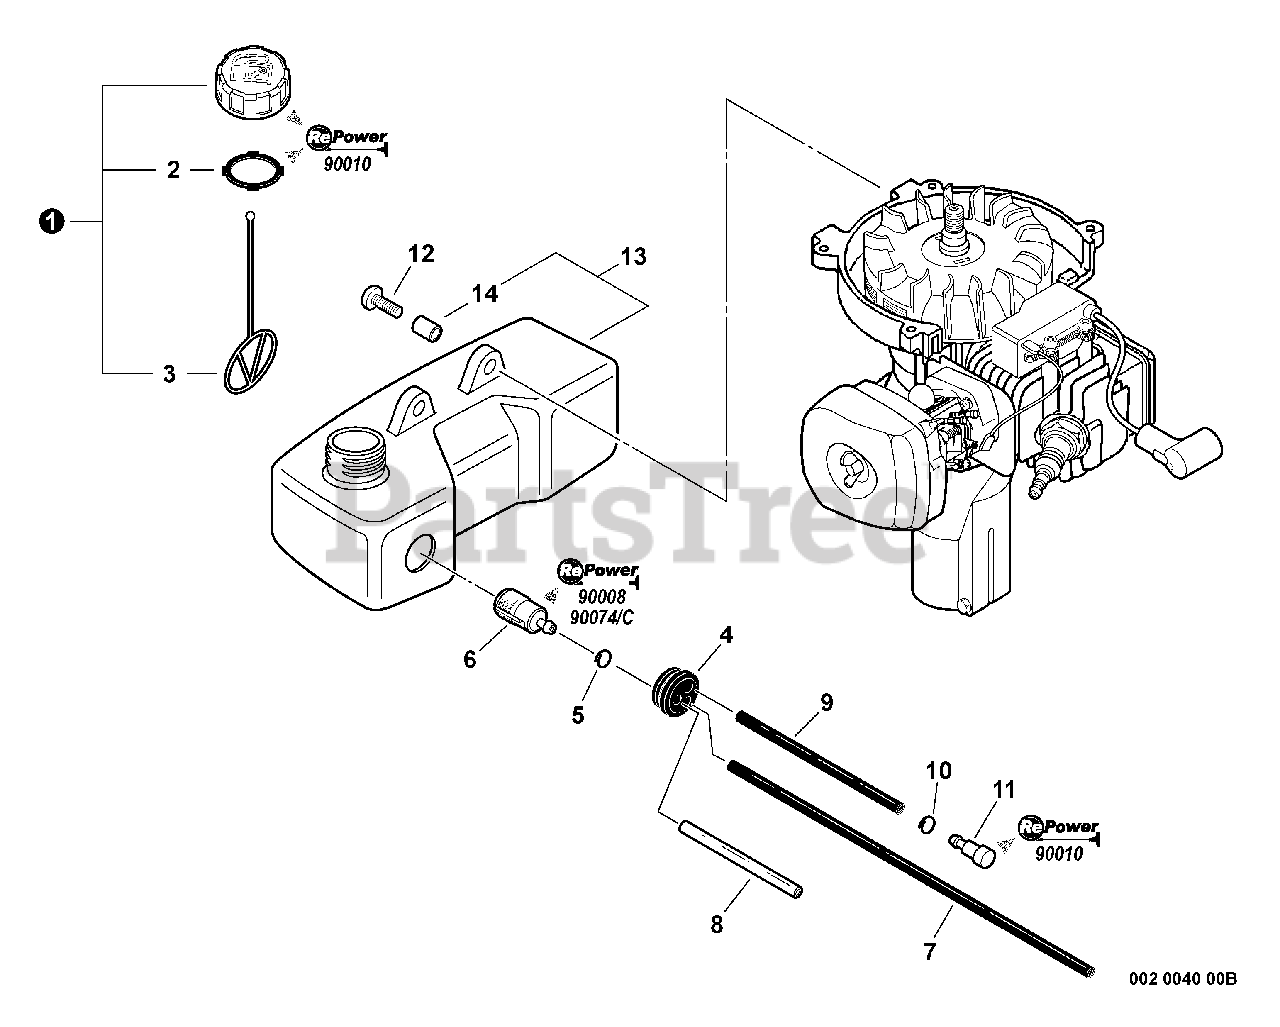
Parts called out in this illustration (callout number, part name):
1	CAP ASSY, FUEL
2	GASKET, FUEL CAP
3	CONNECTOR, CAP L= 100 MM
4	GROMMET, FUEL
5	CLIP 6 MM
6	FILTER, FUEL
7	PIPE, FUEL 3×5×210 BLACK
8	PIPE, FUEL 3×6×50
9	PIPE, FUEL 3x-5x-70 BLACK
11	VENT ASSY
12	SCREW 5×15
13	TANK ASSY, FUEL
14	SPACER 6.2×7.8×6
15	TUNE-UP KIT - REPOWER
16	FILTER KIT - REPOWER
17	CAP/VENT KIT - REPOWER
